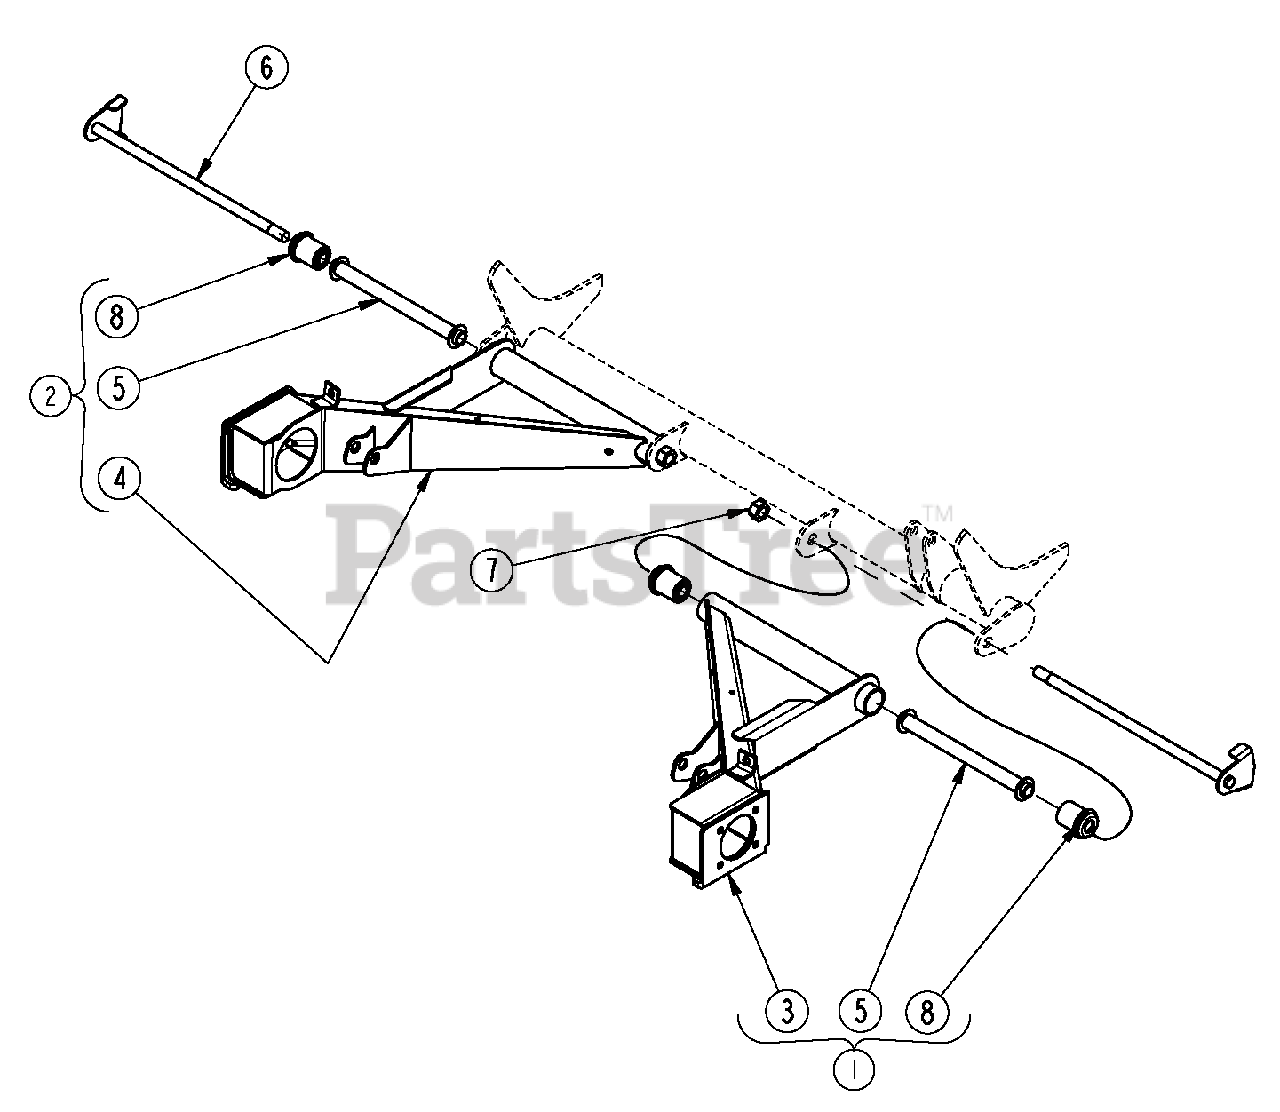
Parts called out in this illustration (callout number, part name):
1	TRAILING ARM RIGHT HAND ASSEMBLY
2	TRAILING ARM LEFT HAND ASSEMBLY
3	TRAILING ARM RIGHT HAND WELDMENT
4	TRAILING ARM LEFT HAND WELDMENT
5	CENTER PIVOT TUBE WELDMENT
6	TRAILING ARM PIVOT BOLT WLDMNT
7	NUT, TOP LOCK .563-12 GR5 YWZC
8	BUSHING IDLER ARM RUBBER
